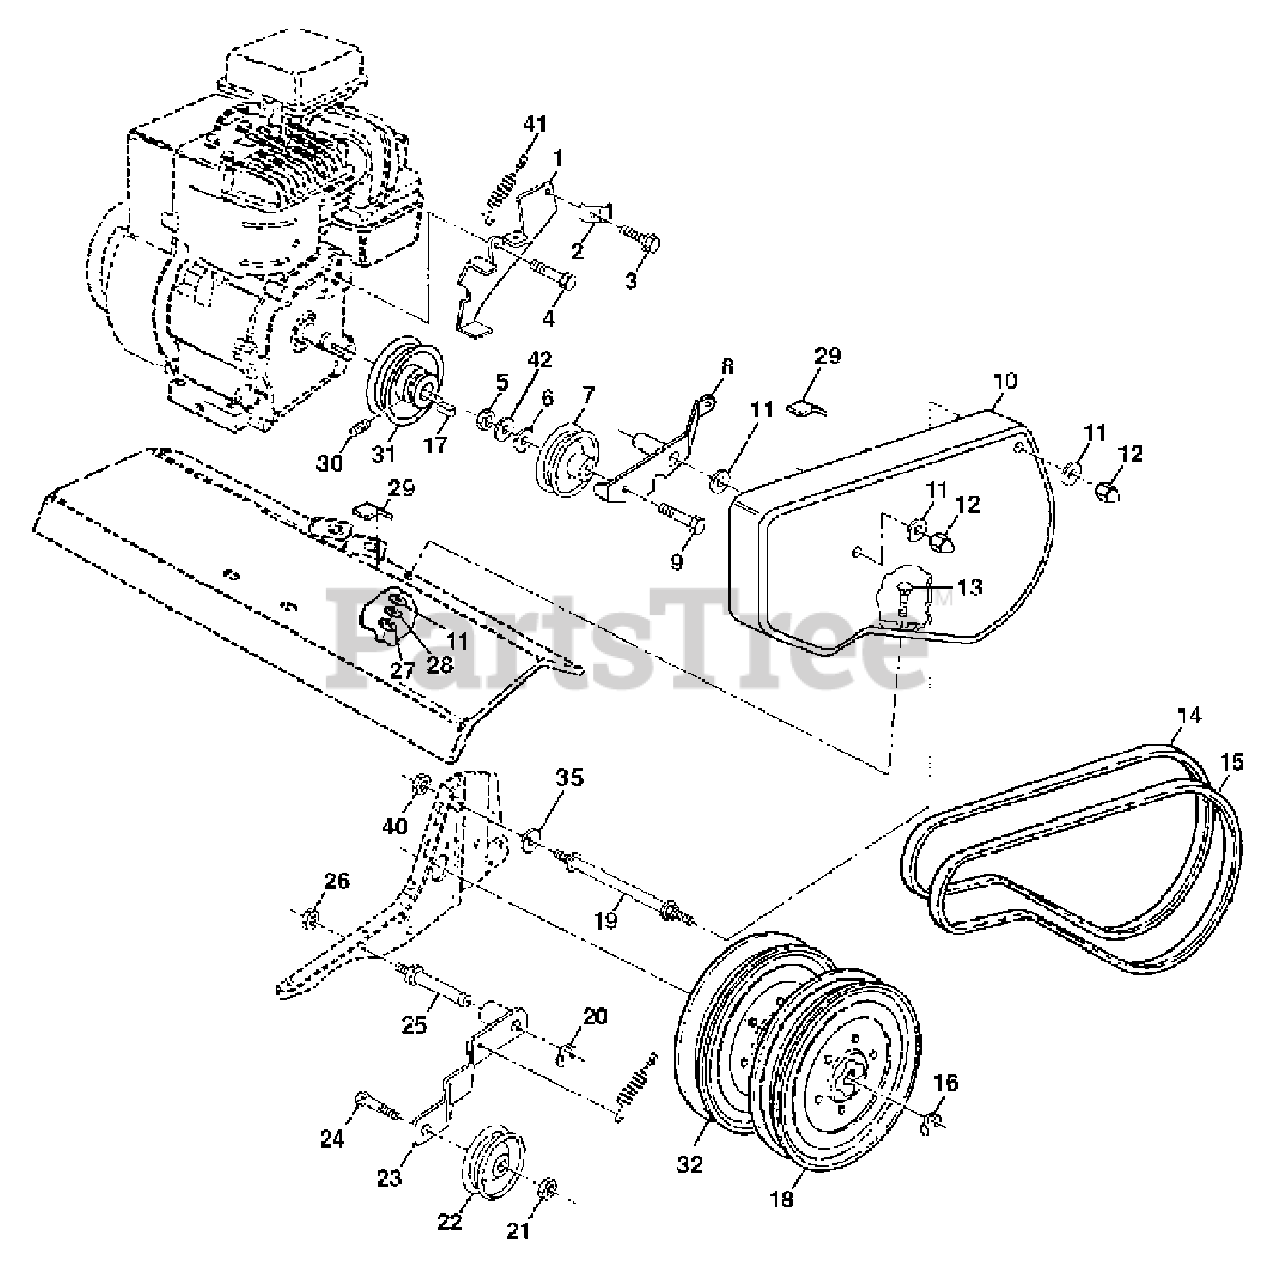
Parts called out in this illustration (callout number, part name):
1	Assembly, Bracket, Belt Guard
2	Clip, Cable
3	Screw, Hex, Washer Hd., Slotted, Thd. Cutting #10-24 x 1/2 Type D
4	Bolt, Hex 1/2-20 x 3/4
5	Nut, Hex Lock 3/8-16
6	Washer 13/32 x 13/16 x 16 Ga.
7	Pulley, Idler, Reverse
8	Assembly, Arm, Reverse Idler
9	Bolt, Hex 3/8-16 x 1-3/4
10	Guard, Belt
11	Washer 9/32 x 5/8 x 16 Ga.
12	Nut, Cap 1/4-20
13	Bolt, Carriage 1/4-20 x 3/4
14	V-Belt (Forward Motion)
15	V-Belt (Reverse)
16	Ring, Retainer
17	Key, Square
18	Pulley, Flat, Trans.
19	Bolt, Belt Guard
20	Ring, Klip
21	Nut, Hex, Jam 3/8-16
22	Pulley, Idler
24	Bolt, Hex 3/8-16 x 1-1/4
25	Shaft, Idler Arm
26	Nut, Hex, Jam 5/16-18
27	Nut, Fin Hex 1/4-20
28	Washer LK Hvy Helical 1/4
29	Pad, Idler
30	Screw, Set , Socket, Headless C.P. 1/4-20 x 1/4
31	Sheave, Engine
32	Pulley, V-Groove, Trans.
40	Nut Keps Hex 1/4-20
41	Spring
42	Spacer
